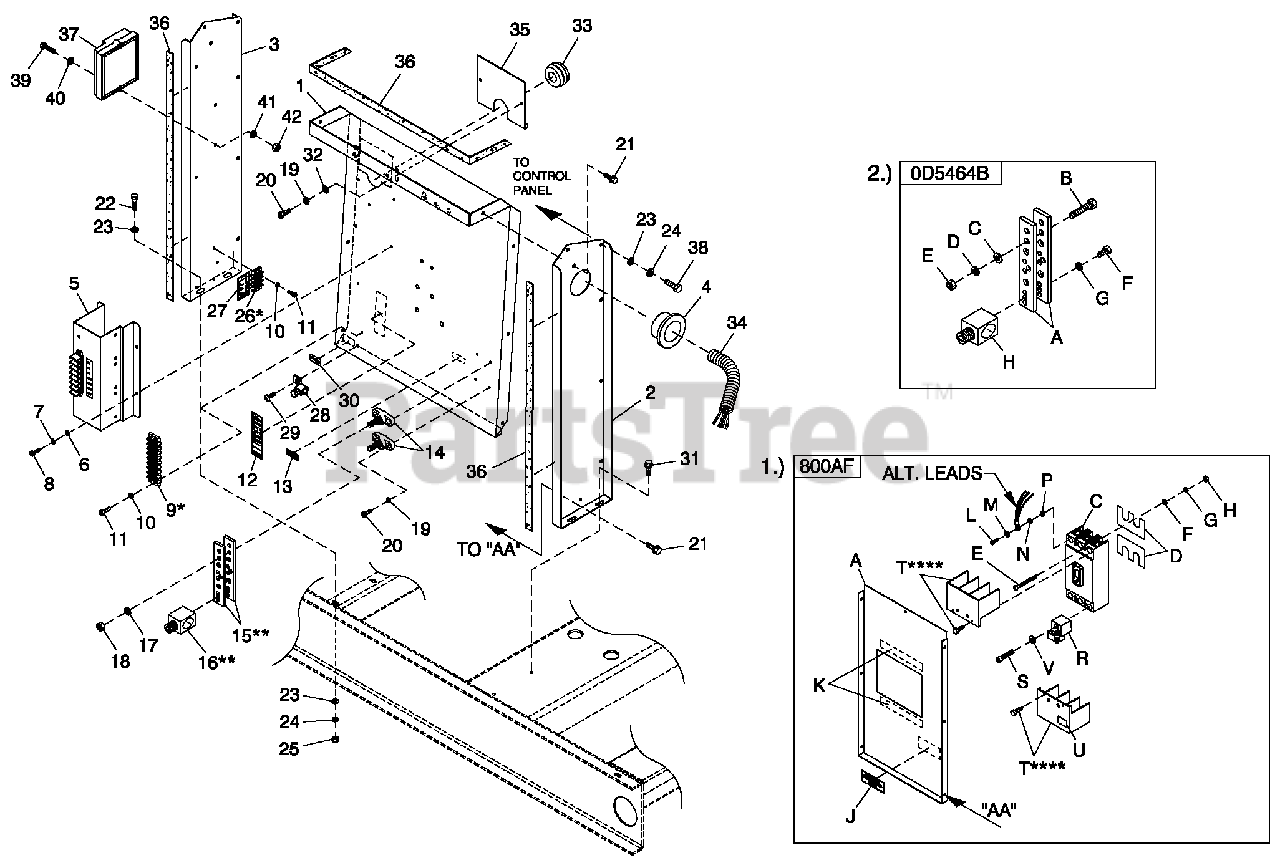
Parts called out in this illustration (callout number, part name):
0G0171A	STAND RH CONTROL CPL C5 2 HOLE
1	PANEL CB CONN BOX
2	STAND RH CONTROL CPL C5
3	STAND LH CONTROL CPL C5
4	BUSHING SNAP SB-2.5-31
5	ASSY PCB INTERFACE 1PH 240V
6	WASHER FLAT M4
7	WASHER LOCK #8-M4
8	SCREW PHTT M4-0.7 X 10 ZYC
9	BLOCK TERM 2 0 A 8 X 6 X 1100V
10	WASHER LOCK #6
11	SCREW PHTT #6-32X1/2 ZYC
12	DECAL CPL CUST CONN H CTRL
13	DECAL NEUTRAL
14	JUNCTION BLOCK 3/8-16
15	BUS BAR NEUTRAL BLOCK 390
16	LUG SLDLSS 600/250-1/0 X 1/4-28
17	WASHER LOCK 3/8
18	NUT HEX 3/8-16 STEEL
19	WASHER LOCK M5
20	SCREW PHTT M5-0.8X 16 ZYC
21	SCREW THF M6-1 X 16 N WA Z/JS
22	SCREW HHC M6-1.0X 20 G8.8
23	WASHER FLAT 1/4-M6 ZINC
24	WASHER LOCK M6-1/4
25	NUT HEX M6X 1.0 G8YEL CHR
26	BLOCK TERM 2 0 A 6 X 3 X 1100V
27	DECAL CUST CONN 120V UTILITY
28	LUG SLDLSS #6-14X 13/64CU
29	SCREW HHTT #10-32X3/8 CZ
30	DECAL GROUND LUG
31	SCREW HHTT M6-1.0X16ZYC
32	WASHER FLAT M5
33	GROMMET 1.25 X .25 X .75
34	CONDUIT FLEX 2.0" ID
35	PLATE WIRE SNGLGALV
36	TAPE ELEC 1/2 FOAM (AS REQ'D)
37	ASSY PCB HSB CTRL IGN MODULE
38	SCREW HHC M6-1.0X16G8.8
39	SCREW PPHM #10/32X2
40	WASHER FLAT #10 ZINC
41	WASHER LOCK #10
42	NUT HEX #10-32 STEEL
A	COVER, CB 803 C5
C	CIRCUIT BREAKERS 800A FRAME
D	INSULCB800AF
E	SCREW RHM 1/4-20X1-1/2
F	WASHER FLAT 1/4-M6 ZINC
G	WASHER LOCK M6-1/4
H	NUT HEX 1/4-20 STEEL
J	DECAL CUSTOMER CONNECT INSIDE
K	TAPE ELEC 1/2 FOAM
L	SCREW SHC M 10-1.50 X 40 G12.9
M	WASHER FLAT 3/8-M10 ZINC
N	WASHER LOCK 3/8
P	NUT HEX M10-1.5G8YEL CHR
R	LUG SLDLSS 3/0-400X3 MCM AL/CU
S	SCREW SHC M6-1.0X 50 G8.8
T	TERM. COVER VITZROTECH 400AF CB
U	DECAL TERMINAL SHOCK HZD BI
V	WASHER LOCK M6-1/4
A	BUS BAR NEUTRAL BLOCK 390
B	SCREW HHC M8-1.25 X 45 G8.8 FT
C	WASHER FLAT 5/16-M8 ZINC
D	WASHER LOCK M8-5/16
E	NUT HEX M8-1.25G8YEL CHR
F	SCREW HHC 1/4-28 X 3/4 G5
G	WASHER LOCK 1/4-M6SS
H	LUG SLDLSS 600/250-1/0 X 1/4-28
